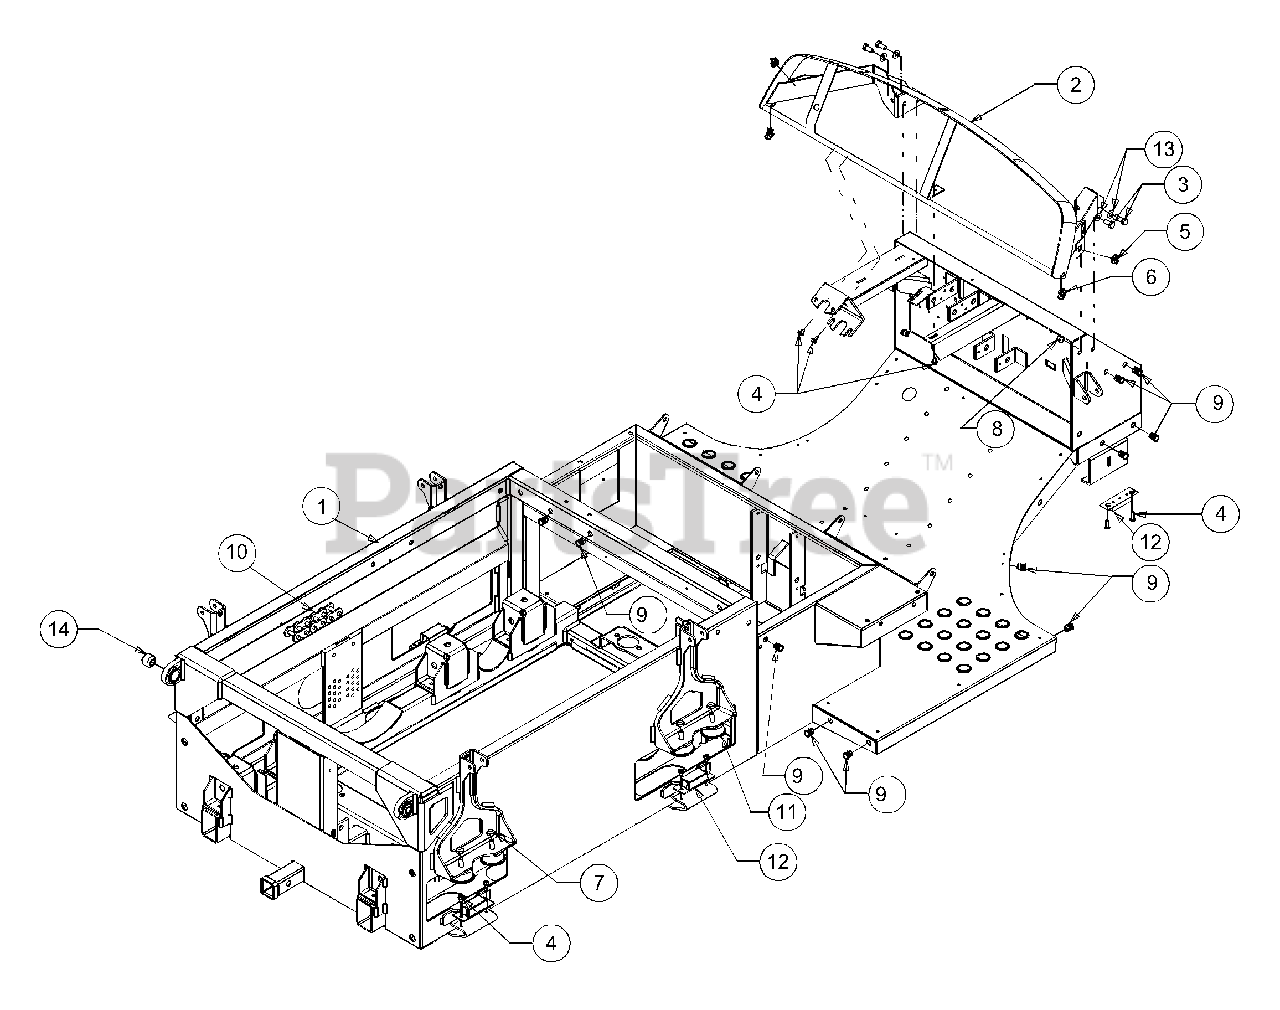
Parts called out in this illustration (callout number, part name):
1	Frame Assembly, Complete
4	Screw, Self-tapping, 1/4-20 x 0.500
5	Nut, Retainer, 5/16-18
6	U-Nut, 1/4-20
7	Nut, Nylon Lock, M10-1.25
8	Nut, Flange Lock, 3/8-16
9	Nut, Insert, 5/16-18
10	Chain, 60-97 Pitch
11	Bumper, Compression Suspension
12	Bumper, Compression Extension
13	Washer, Flat, .406 x 812 x .51
14	Rubber Bushing, Bed Pivot
